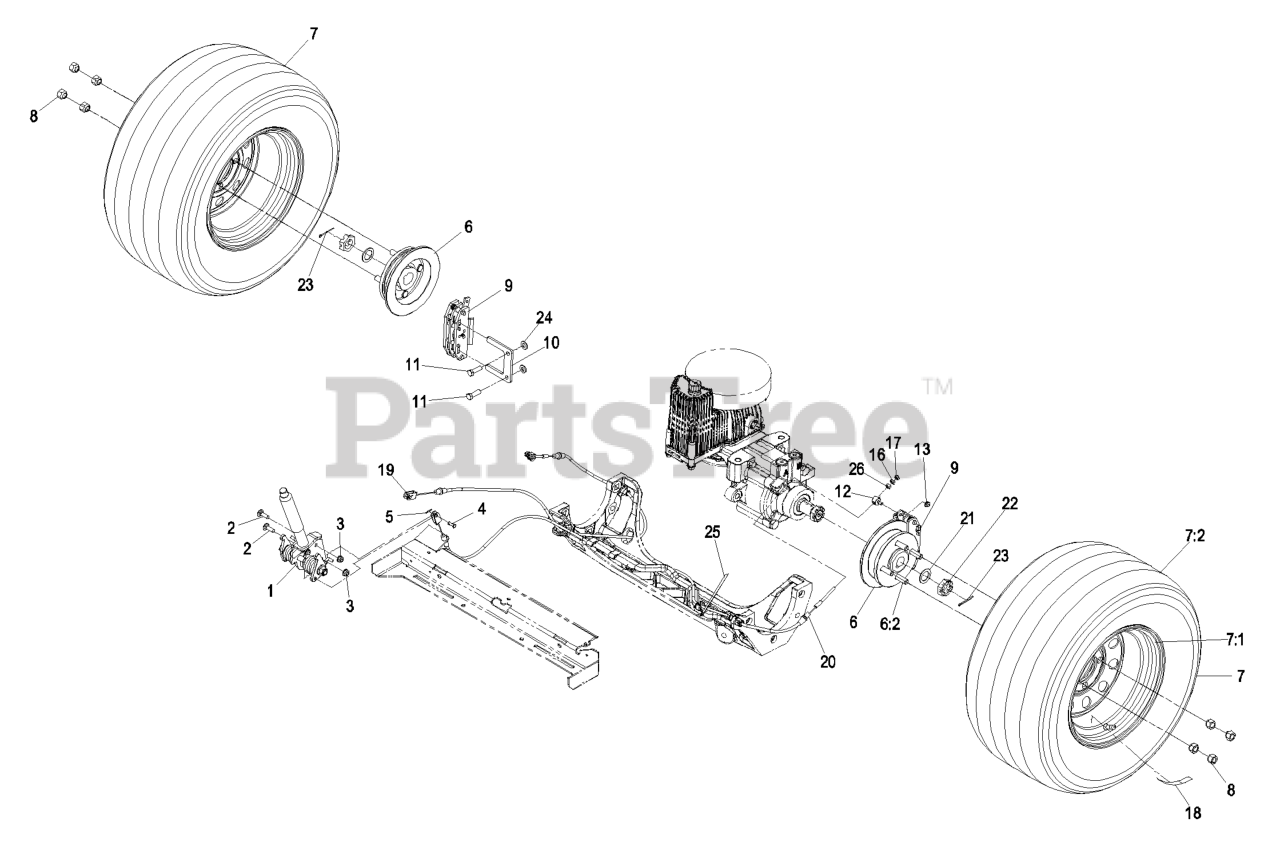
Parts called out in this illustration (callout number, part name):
2	BOLT-CARR
3	NUT-HF, NI
4	PIN-CLEVIS
5	PIN-COTTER
6:2	STUD-WHEEL
7	WHEEL AND TIRE ASM
7:1	RIM ASM
7:2	TIRE
8	NUT-LUG
9	CALIPER-BRAKE
10	PLATE-MOUNT, BRAKE
11	SCREW-HH
16	NUT-JAM
17	NUT-LOCK, NI
18	DECAL-HUB, WHEEL
21	WASHER-SPACER
23	PIN-COTTER
24	WASHER-FLAT
25	TIE-CABLE
26	NUT-HEX
